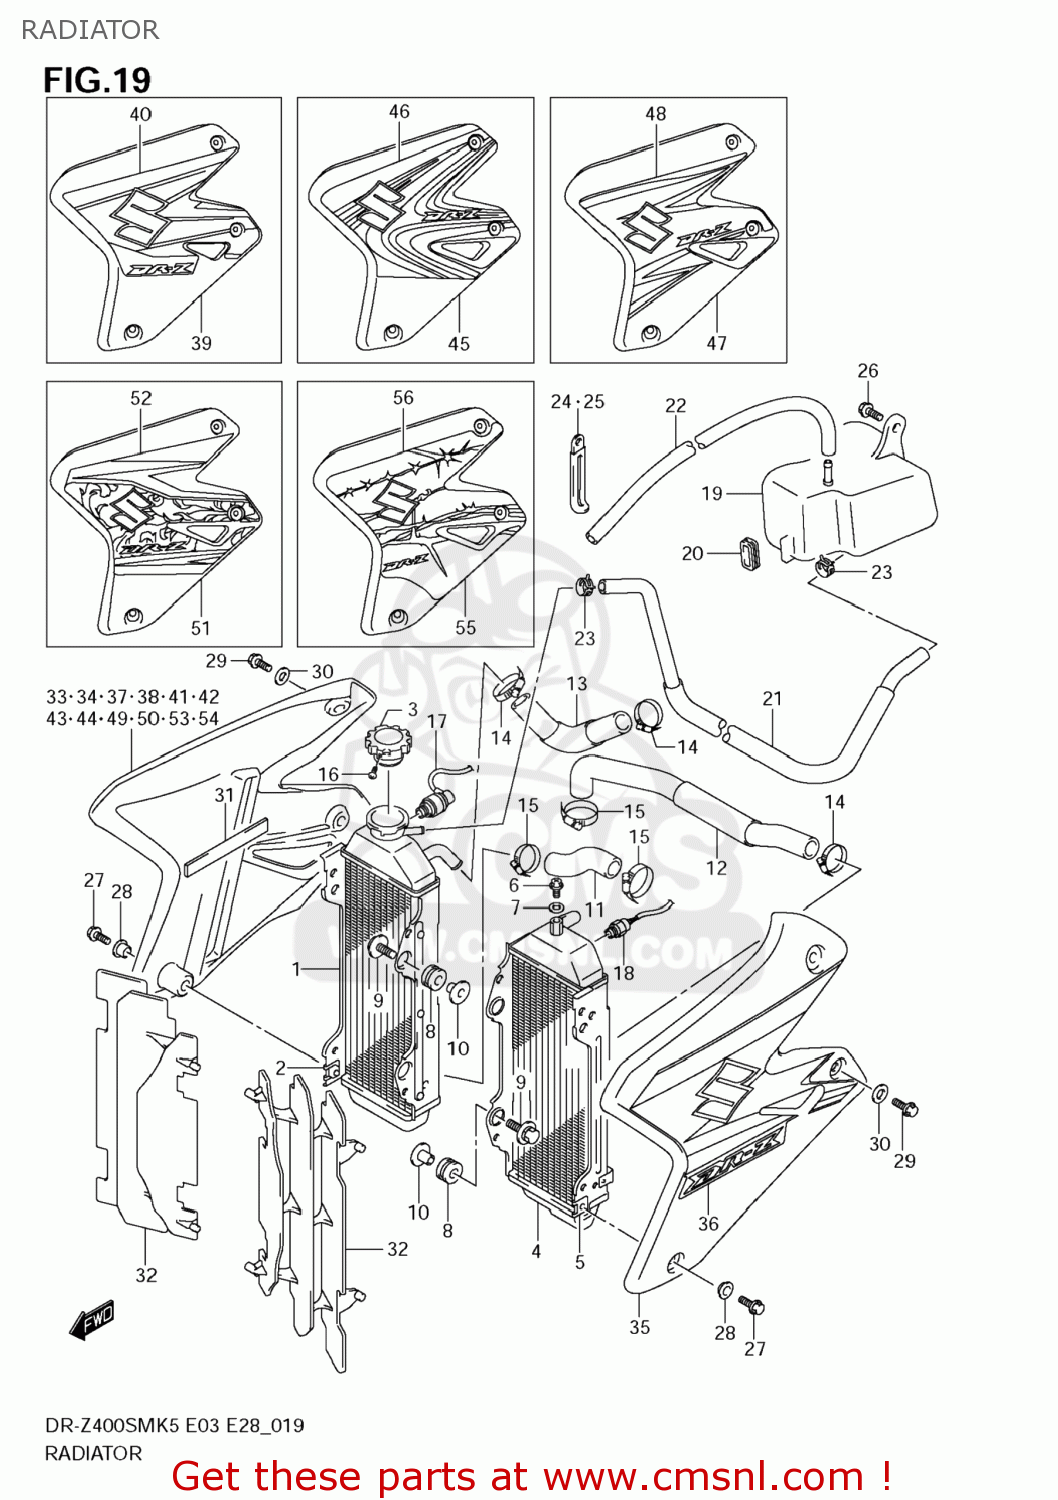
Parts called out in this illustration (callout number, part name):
1	RADIATOR COMP,
2	NUT
3	CAP,RADIATOR(1.1)
4	RADIATOR COMP,
5	NUT
6	UNION BOLT,AIR VENT
7	GASKET(6.4X11.5X0.8) (NAS)
8	CUSHION,RADIATOR LWR
9	BOLT(6X25)
10	SPACER(6.5X10.5X14.1)
11	HOSE,RADIATOR INLET
12	HOSE,RADIATOR OUTLET
13	HOSE,RADIATOR JOINT
14	CLAMP
15	CLAMP
16	SCREW,RADIATOR CAP
17	SWITCH ASSY,WATER TEMP
18	SWITCH,FAN
19	TANK,RESERVOIR
20	CUSHION,RESERVOIR TANK
21	HOSE,RESERVOIR TANK INLET
22	HOSE(5X9X2000)
23	CLIP
24	CLAMP(L:45 T:0.6)
25	CLAMP(L:45)
26	BOLT
27	BOLT(6X16)
28	WASHER
29	BOLT(6X8)
30	WASHER(6.5X14X1.6)
31	CUSHION,TOOL HOLDER
32	LOUVER,RADIATOR
33	COVER,RADIATOR,R(BLACK)
34	TAPE,RADIATOR COVER,R
35	COVER,RADIATOR,L(BLACK)
36	TAPE,RADIATOR COVER,L
37	COVER,RADIATOR,R(BLACK)
38	TAPE,RADIATOR COVER,R
39	COVER,RADIATOR,L(BLACK)
40	TAPE,RADIATOR COVER,L
41	COVER,RADIATOR,R(BLUE)
42	TAPE,RADIATOR COVER,R
43	COVER,RADIATOR,R(YELLOW)
44	TAPE,RADIATOR COVER,R
45	COVER,RADIATOR,L(BLUE)
46	TAPE,RADIATOR COVER,L
47	COVER,RADIATOR,L(YELLOW)
48	TAPE,RADIATOR COVER,L
49	COVER,RADIATOR,R(WHITE)
50	TAPE,RADIATOR COVER,R
51	COVER,RADIATOR,L(WHITE)
52	TAPE,RADIATOR COVER,L
53	COVER,RADIATOR,R(WHITE)
54	TAPE,RADIATOR COVER,R
55	COVER,RADIATOR,L(WHITE)
56	TAPE,RADIATOR COVER,L
